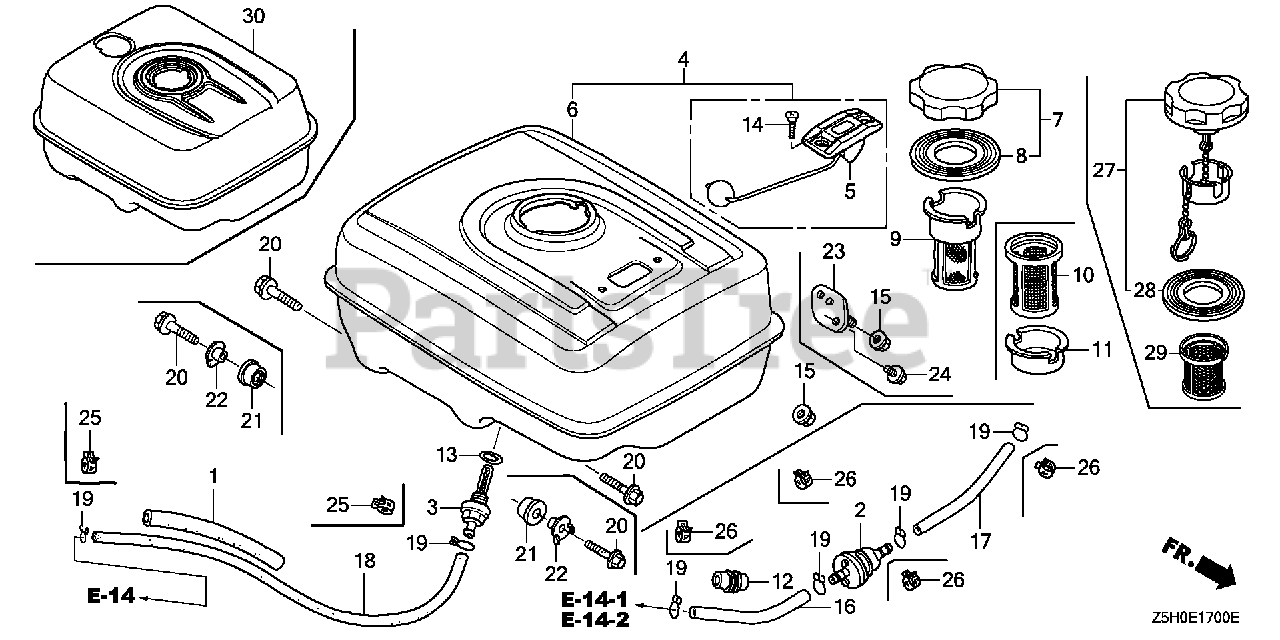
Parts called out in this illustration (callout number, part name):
1	RUBBER, SUPPORTER (107MM)
3	JOINT, FUEL TANK
6	TANK, FUEL *NH105* (MAT BLACK)
6	TANK, FUEL *NH1* (BLACK)
6	TANK, FUEL *NH31* (MCKINLEY WHITE)
7	CAP, FUEL FILLER (CHROME PLATED)
8	GASKET, FUEL FILLER CAP (39X62X3) (TOUYOUSYA)
9	FILTER, FUEL
13	O-RING (13.5X1.5) (ARAI)
13	O-RING (14MM) (NOK)
15	NUT, FLANGE (8MM)
18	TUBE, FUEL (4.5X222) (FKM)
18	BULK HOSE, FUEL (4.5X3000) (4.5X222)
19	CLIP, TUBE (B8)
20	BOLT, FLANGE (8X25)
25	CLAMP, TUBE (D8)
27	CAP, FUEL FILLER (CHROME PLATED)
27	CAP, FUEL FILLER
28	GASKET, FUEL FILLER CAP (39X62X3) (RADICON)
28	GASKET, FUEL FILLER CAP (39X62X3)
29	FILTER, FUEL (FROM 1204807)
